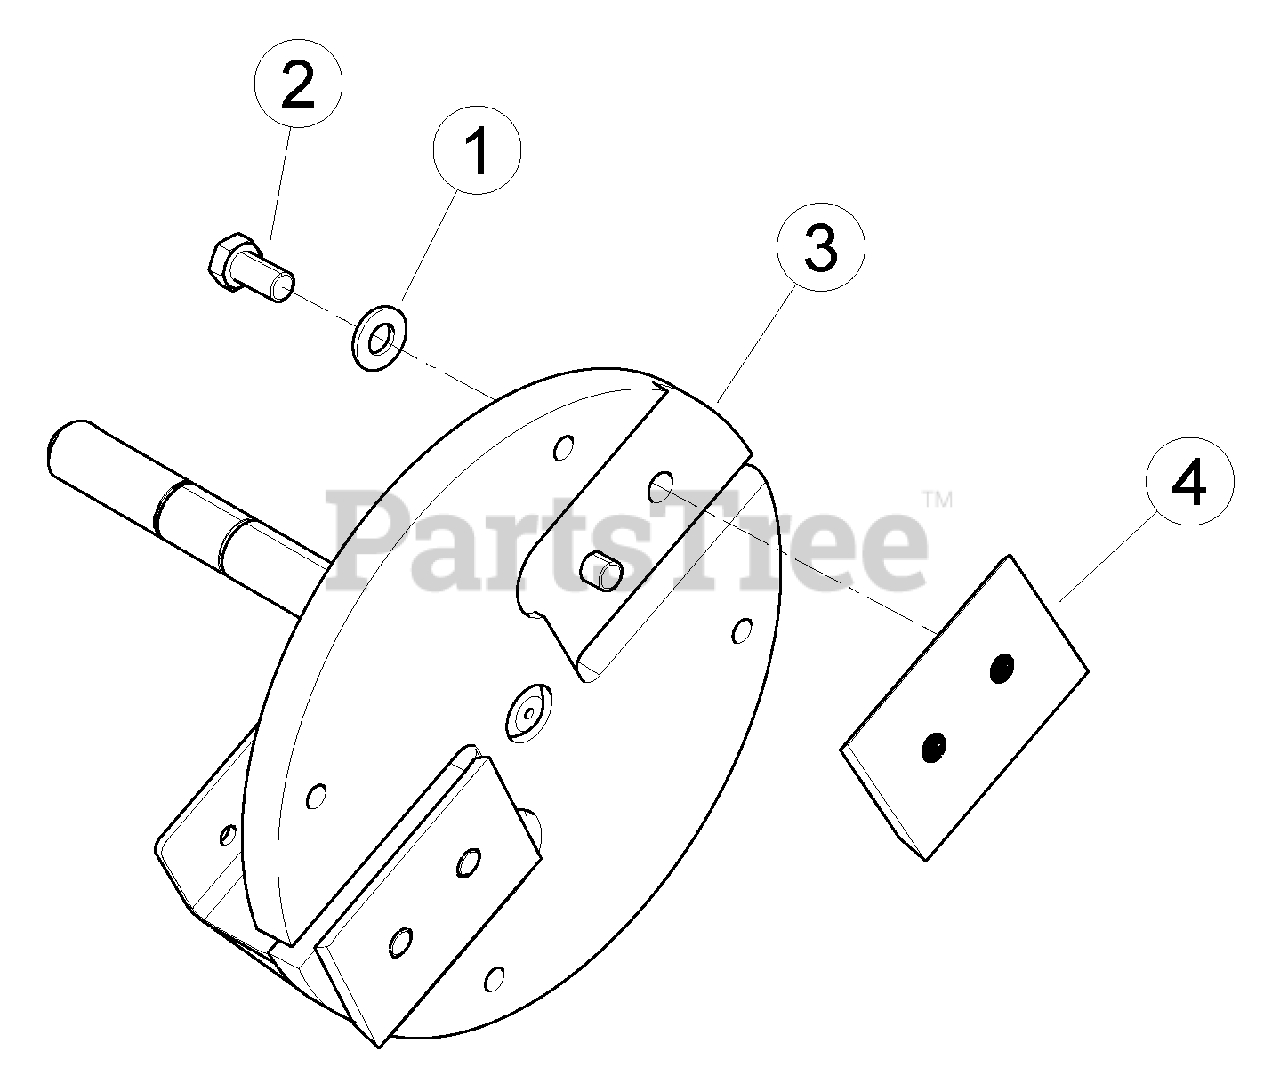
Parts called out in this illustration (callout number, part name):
1	WASHER, 5/8 SAE HARDENED
2	BOLT, M16 X 2.0 X 30 HEX HD W/ PATCH
3	WELDMENT, 4-1/2 CHIPPER ROTOR
4	KIT, CHIPPER BLADE
